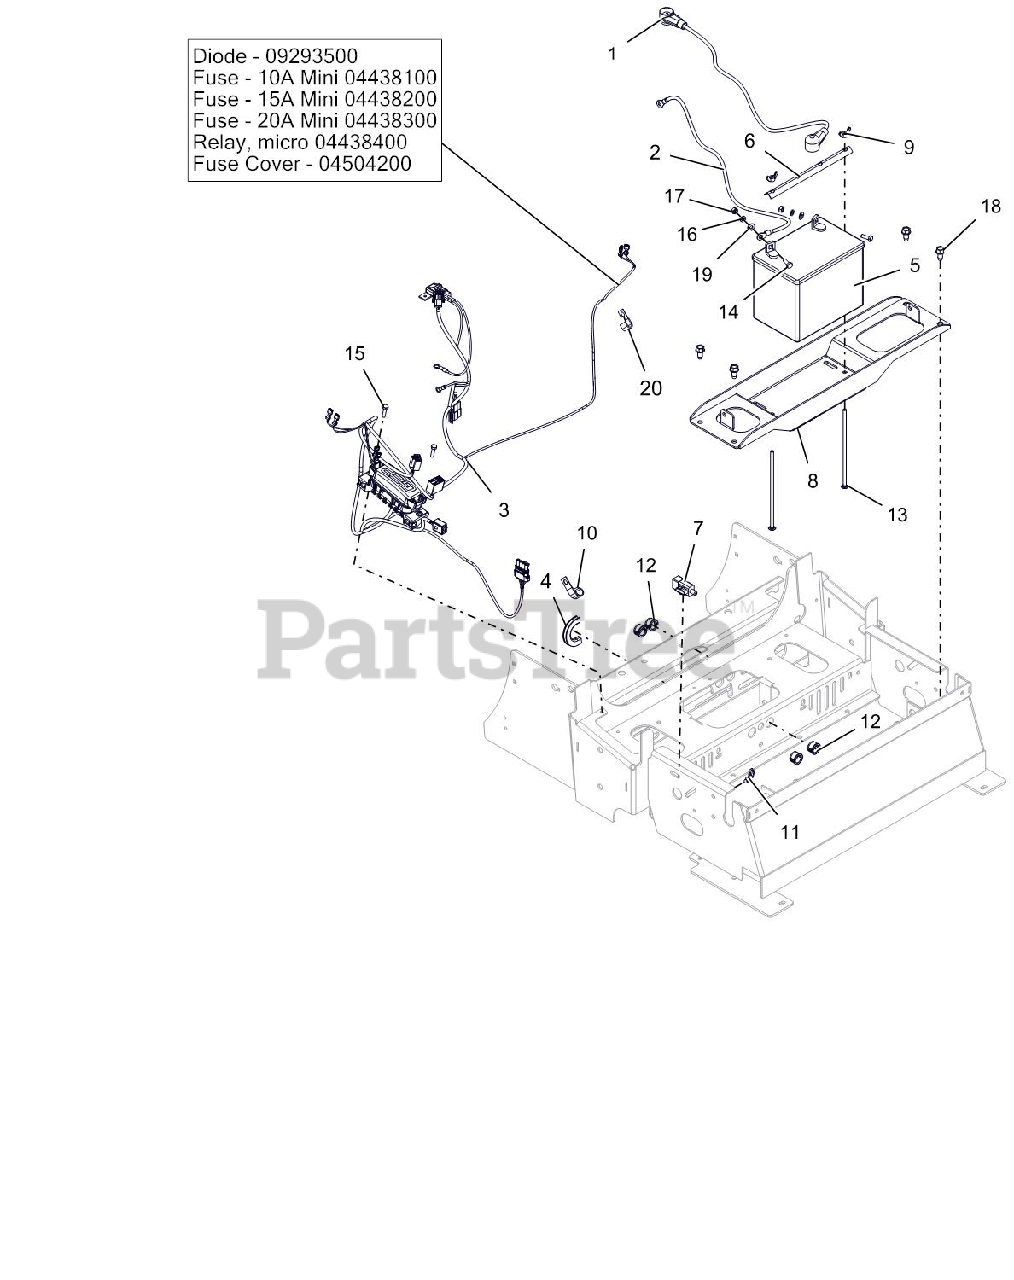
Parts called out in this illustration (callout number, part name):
1	CABLE - POS BATT W/BOOTS 6X35
2	CABLE-NEGATIVE BATTERY 35.00"
3	DIODE, CONNECTOR SHELL
3	FUSE,10 AMP MINI-ATC
3	FUSE,20 AMP MINI ATC
3	RELAY,MICRO5 TERML W/RESISTOR
3	COVER, HARNESS FUSE/RELAY MOD
3	FUSE,15 AMP MINI-ATC
3	HARNESS, PT400 WIRING
4	STRIP, COWL
5	BATTERY, 300 CCA 10U1L
6	HOLD DOWN
7	SWITCH, SNAP IN - N.O./N.O.
8	PT400 GAS BATTERY TRAY - RED
9	NUT-LK WING .250-20 YWZC
11	CABLE TIE W/ TREE (.25 HOLE)
12	BUSH, PANEL SNAP .687X.875X.56
13	BLT-RDHDSQNK .25-20X7.50 GR2YZ
14	@BLT-HEX .25-20X.75 GR5 YWZC
15	@BLT-HEX M6-1.0X25 YWZC
16	@WSHR-LK .25X.062 REG YWZC
17	@NUT-HEX .25-20 YWZC
18	@SCR-TAP .38-16X.75 HWH TR YWZ
19	@WSHR-FL-STL.281X.62X.065 YWZC
